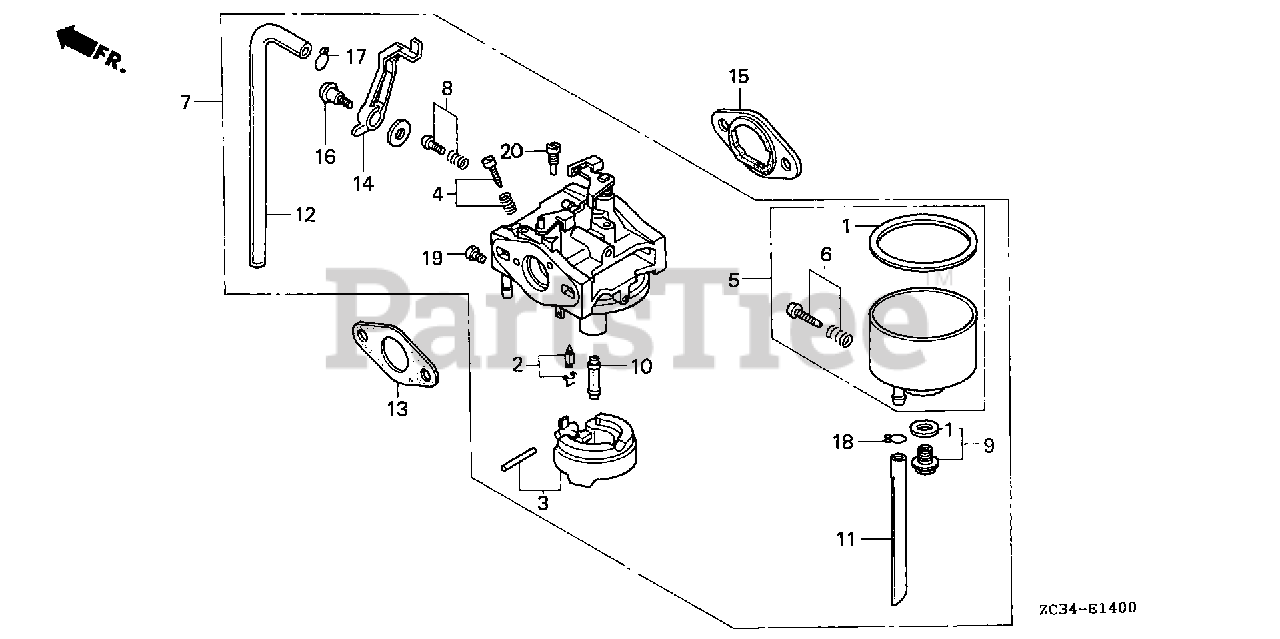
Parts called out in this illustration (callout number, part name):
1	GASKET SET
2	VALVE, FLOAT
4	SCREW SET, PILOT
5	CHAMBER SET, FLOAT
6	SCREW SET, DRAIN
7	CARBURETOR ASSY. (MIKUNI)
8	SCREW SET, STOP
11	TUBE, DRAIN
12	TUBE, AIR VENT
13	GASKET, CARBURETOR
14	LEVER, CHOKE
15	GASKET, AIR CLEANER
16	BOLT, STATOR COVER SETTING
17	CLIP, TUBE
18	CLIP, TUBE
19	JET, MAIN (#55) (ENGINE NO.)
19	JET, MAIN (#57.5)
19	JET, MAIN (#60)
19	JET, MAIN (#62.5)
19	JET, MAIN (#65) (ENGINE NO.)
19	JET, MAIN (#67.5) (ENGINE NO.)
